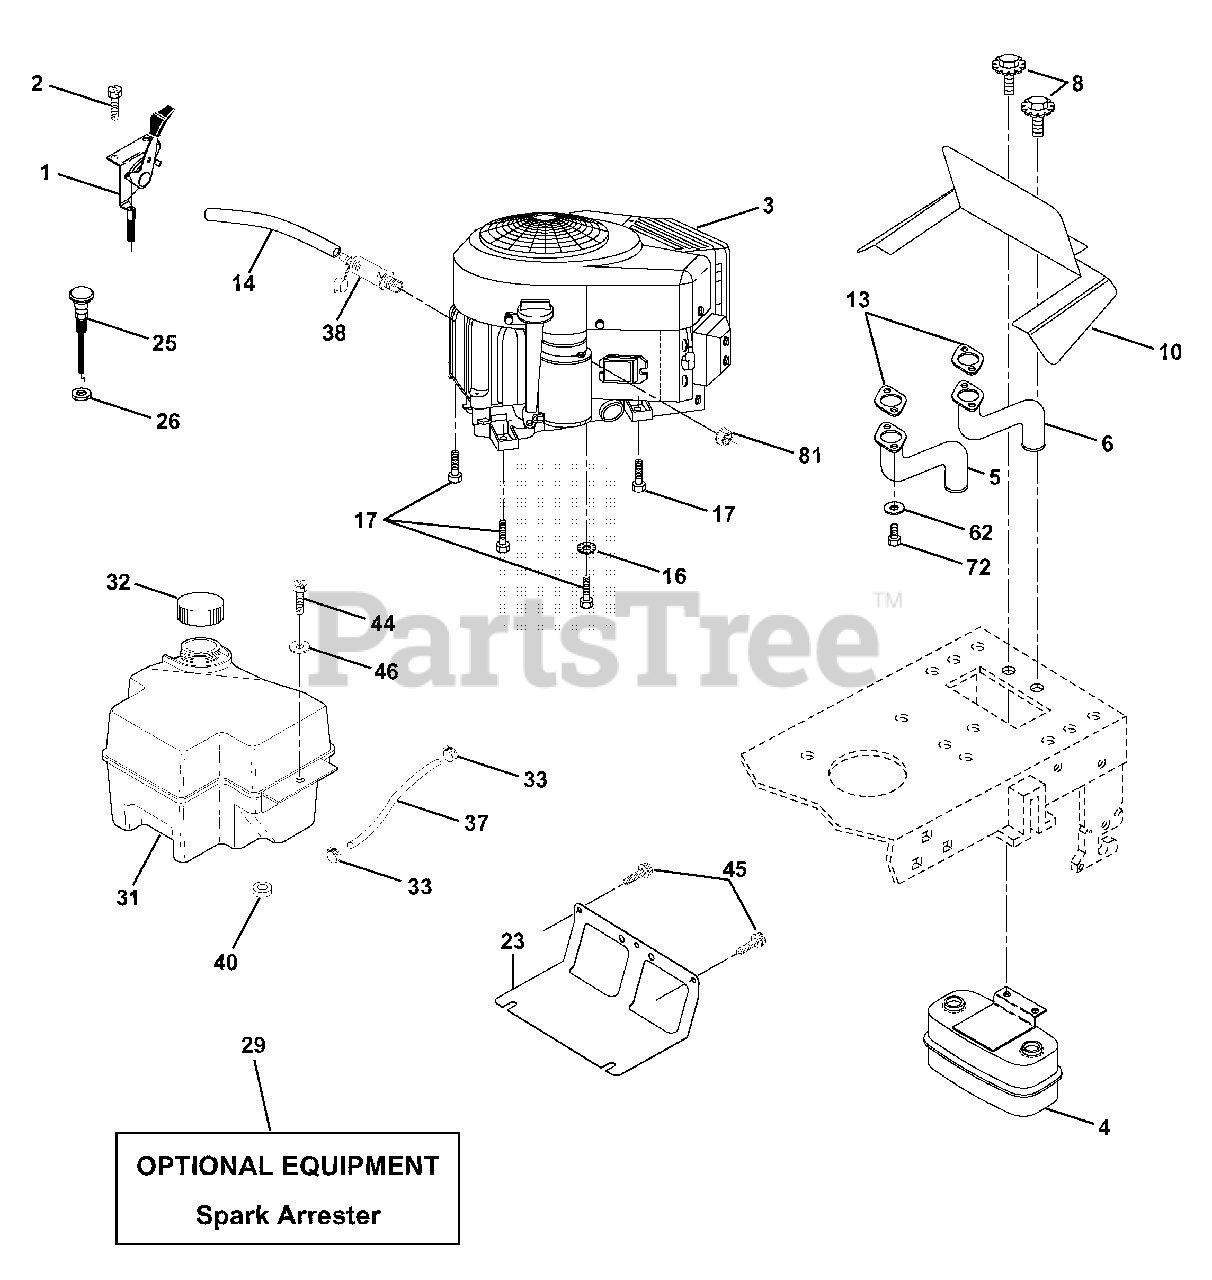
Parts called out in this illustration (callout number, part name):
1	Control, Throttle
2	Screw Hex Thd Cut 1/4-20 x 5/8
4	Muffler, Asm. Twin Lo-Tone
5	Pipe Exhaust Intek 20 RH
6	Pipe Exhaust Intek 20 LH
8	Bolt 5/16-18 UNC x 3/4
10	Shield Browing B&S Intek II
13	Muffler Gasket
14	Tube Drain Oil Easy
16	Washer, Lock Ext tooth 3/8
17	Screw Thdrol 3/8-16 x 1-1/2
23	Shield, Browning/Debris Guard
25	Control Choke
26	Nut Keps 3/8-24 UNF
29	Arrester, Spark
31	Tank, Fuel
32	Cap Gauge, Fuel
33	Clamp, Hose Blk
37	Line, Fuel
38	Plug Drain Oil Easy
40	Bushing Snap Nyl Blk Fuel Line
44	Screw Hexwsh Thdrol 1/4-20 x 3/4
45	Screw Hex Wsh Thdrol 3/8-16 x 3/4
46	Washer 9/32 x 7/8 x 16 Ga.
62	Washer Lock Hvy Hlcl Spr 5/16
72	Screw Hex Hd Cap 5/16-18 x 3/4
81	Nut Keps Hex 1/4-20 Unc
